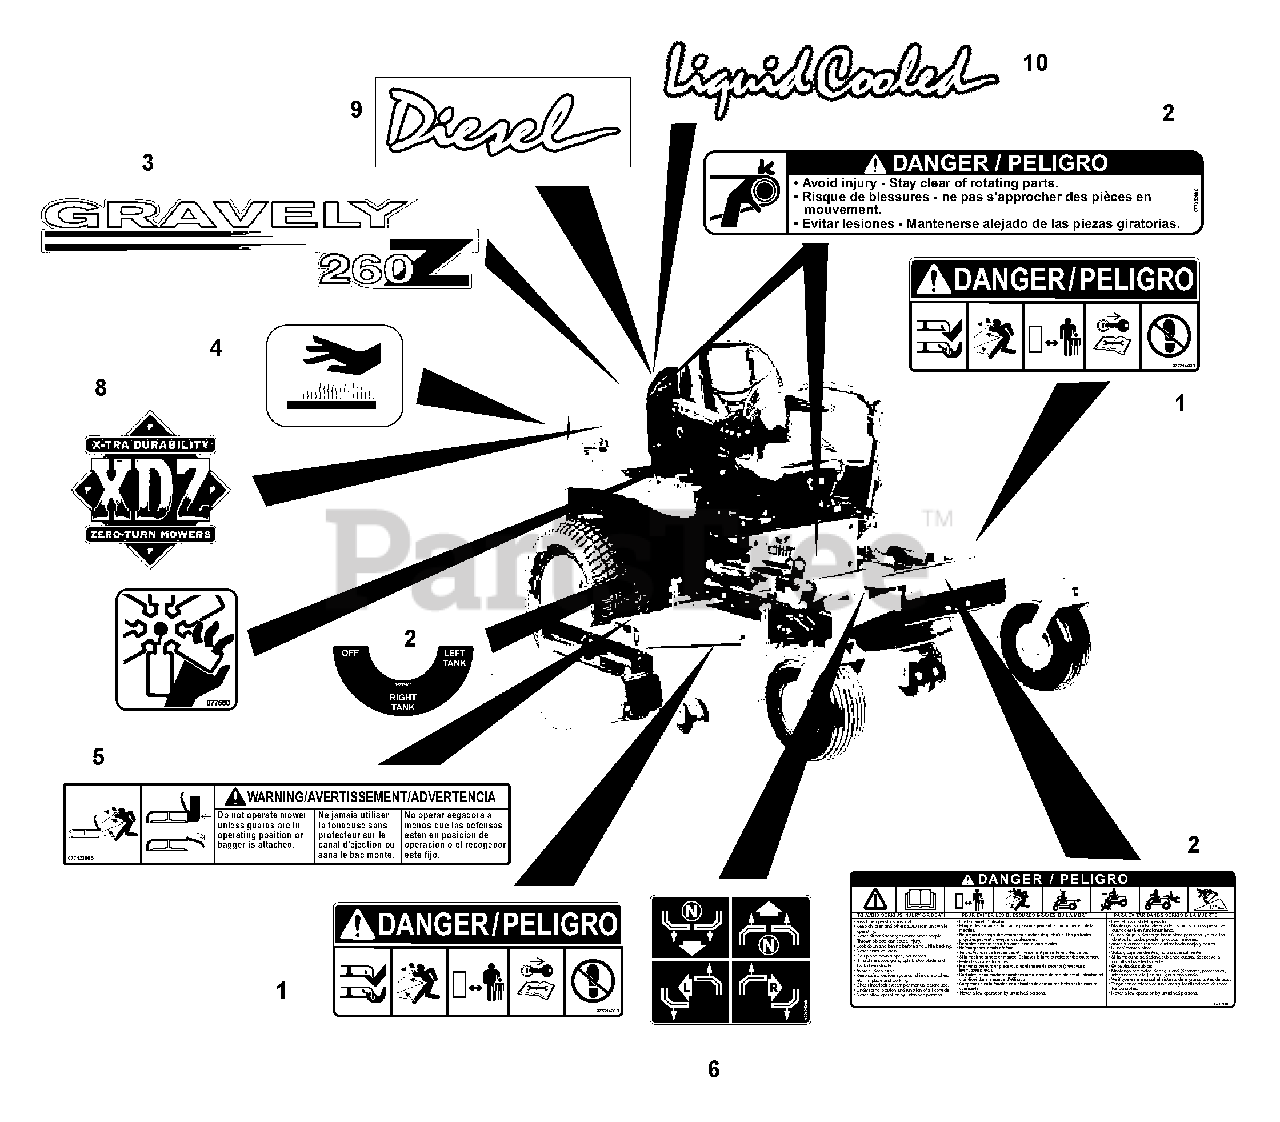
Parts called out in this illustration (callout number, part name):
1	Decal, Mower Pan Head Danger
2	Set, Decal-Common Danger/Fuel
3	Decal, PM-260Z Hood (992156)
3	Decal, PM-272Z Hood (992158)
4	Decal, Hot Surface
5	Decal, Warning
6	Decal, Instructional
7	Decal, Danger Fan
8	Decal, XDZ
9	Decal, Diesel
10	Decal, Liquid Cooled
